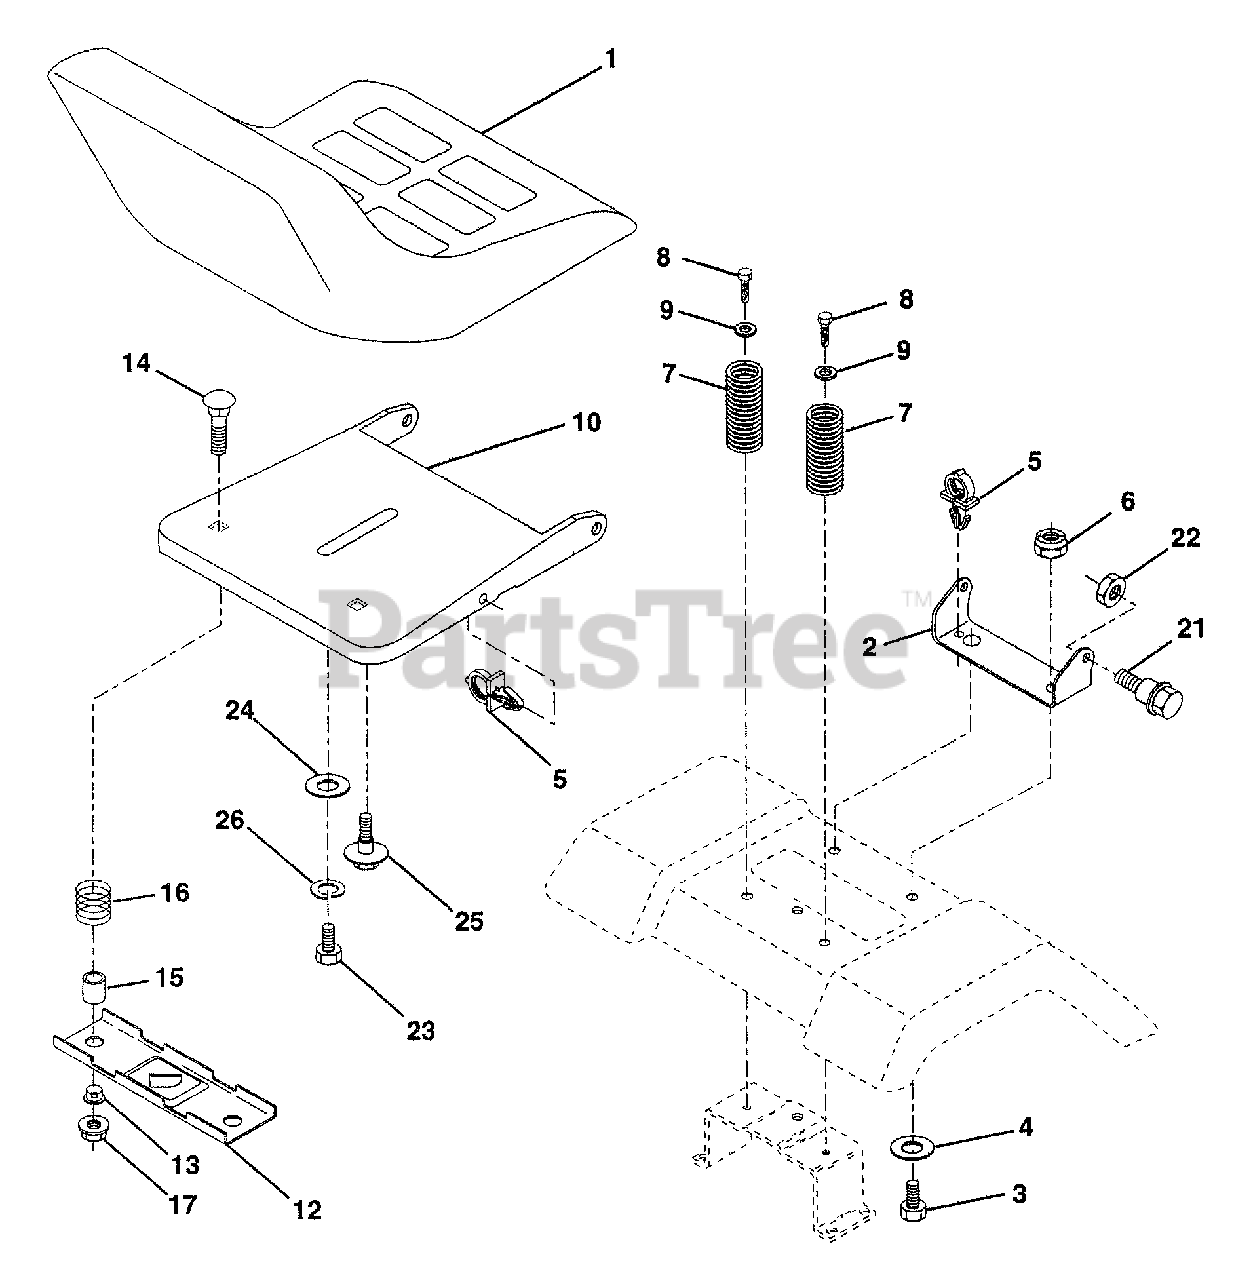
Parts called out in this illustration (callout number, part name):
1	Seat
2	Bracket Pivot Seat 8 720
3	Bolt Fin Hex 3/8-16unc X 1
4	Washer 13/32 X 1 X 10 Ga
5	Clip Push-In
6	Nut Hex w/Ins. 3/8-16 Unc
7	Spring Seat Cprsn 2 250 Blk Zi
8	Screw Thdrol 3/8-16 X 1 Ty-tt
9	Washer 13/32 X 1 X 14 Ga.
10	Pan Seat
12	Bracket Mounting Switch
13	Bushing Snap Blk Nyl 50 Id
14	Bolt Rdhd Sqnk 1/4-20x1-1/2
15	Spacer Split 28x 96 Yel Zinc
16	Spring Cprsn 1 27 Blk Pnt
17	Nut Lock 1/4 Lge Fig Gr 5 Zinc
21	Bolt Shoulder 5/16-18 Unc
22	Nut Hex Lock W/Ins 5/16-18
23	Bolt, Hex Head, Fin 1 /2-13 x 7/8 Grade 5
24	Washer 17/32 X 1-3/16 X 12 Ga.
25	Bolt Shoulder 5/16-18 X 62
26	Washer Lock
